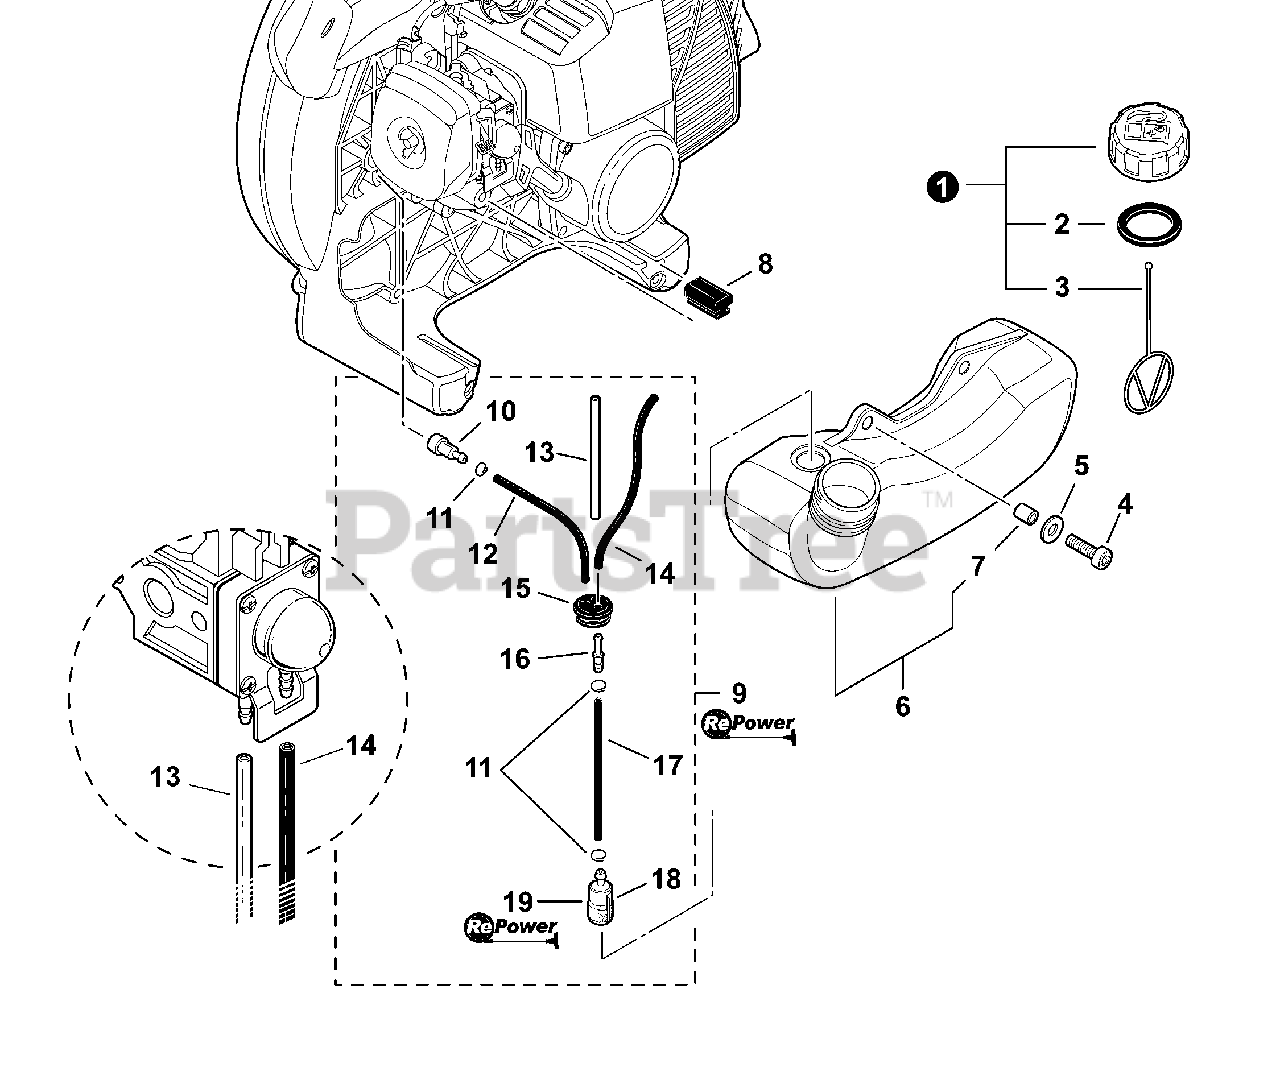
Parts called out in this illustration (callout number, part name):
1	CAP ASSY - ORANGE
2	CONNECTOR, CAP
3	GASKET, CAP
4	SCREW - 5×16
5	WASHER - 5
6	FUEL TANK ASSY
9	RePower FUEL SYSTEM KIT
10	VENT, FUEL TANK
11	CLIP - 6
12	PIPE - 3×6×80 -- BLACK
13	PIPE - 3×6×85 -- CLEAR
14	PIPE - 3×5×78 -- BLACK
16	CONNECTOR, FUEL PIPE
17	PIPE - 3×5×130 -- BLACK
18	FILTER, FUEL
19	RePower TUNE-UP KIT
